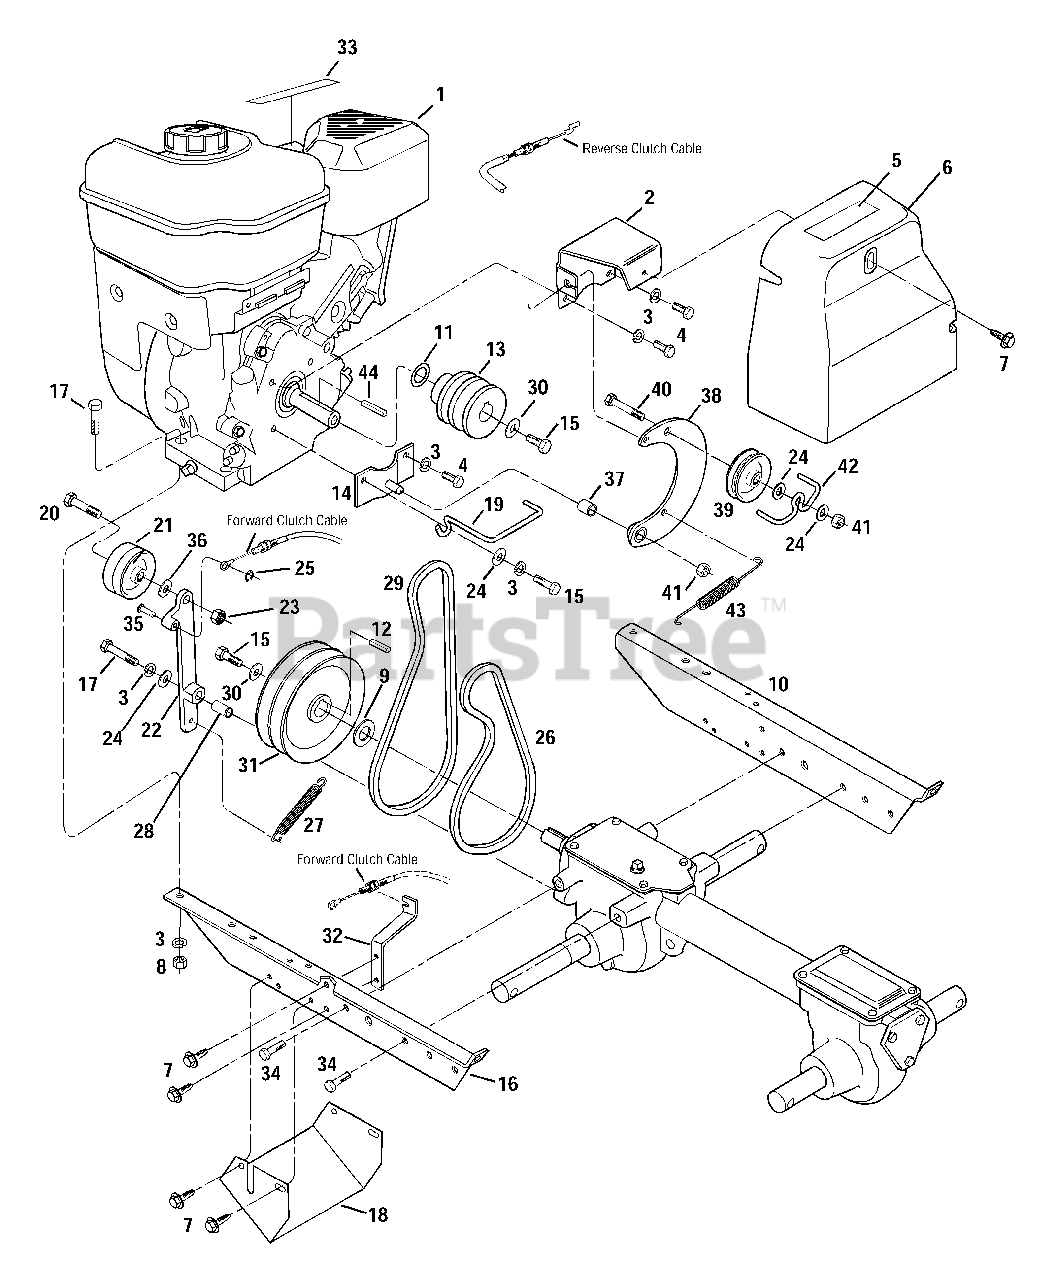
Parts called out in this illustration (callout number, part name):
1	Engine, Recoil Start
2	Bracket, Belt Cover
3	Lockwasher, 5/16
4	Screw, Hex Hd., 5/16-24 x 1/2
5	Decal-Warning, Hot Surfaces
6	Belt Cover
7	Flange Screw, Self-Tapping, 1/4-20 x 1/2
8	Hex Nut, 5/16-18
9	Support Washer
10	Engine Bracket, Right
11	Shim
12	Key, 3/16" x 1"
13	Pulley, Engine Drive
14	Bracket, Reverse Idler
15	Hex Screw, 5/16-24 x 1
16	Engine Bracket, Left
17	Hex Screw, 5/16-18 x 1-1/2
18	Guard, Belts/Pulleys
19	Belt Guide, Forward
20	Hex Screw, 3/8-16 x 1-1/2
21	Forward Idler Pulley
22	Forward Idler Lever
23	Locknut-3/8-16
24	Washer, Flat
25	Klip Ring
26	Forward Drive Belt
27	Spring, Forward Return
28	Bushing, Forward Idler Lever
29	Reverse Drive Belt
30	Washer, Belleville
31	Pulley, Transmission
32	Bracket, Cable Mounting
33	Decal-Stabilization
34	Hex Screw, 5/16-18 x 5/8
35	Clevis Pin
36	Flat Washer, 3/8
37	Bushing
38	Reverse Idler Arm
39	Pulley, Reverse Idler
40	Hex Screw, 5/16-18 x 2
41	Locknut, 5/16-18
42	Belt Guide
43	Spring, Reverse Return
44	Key, 3/16 x 1-1/2
